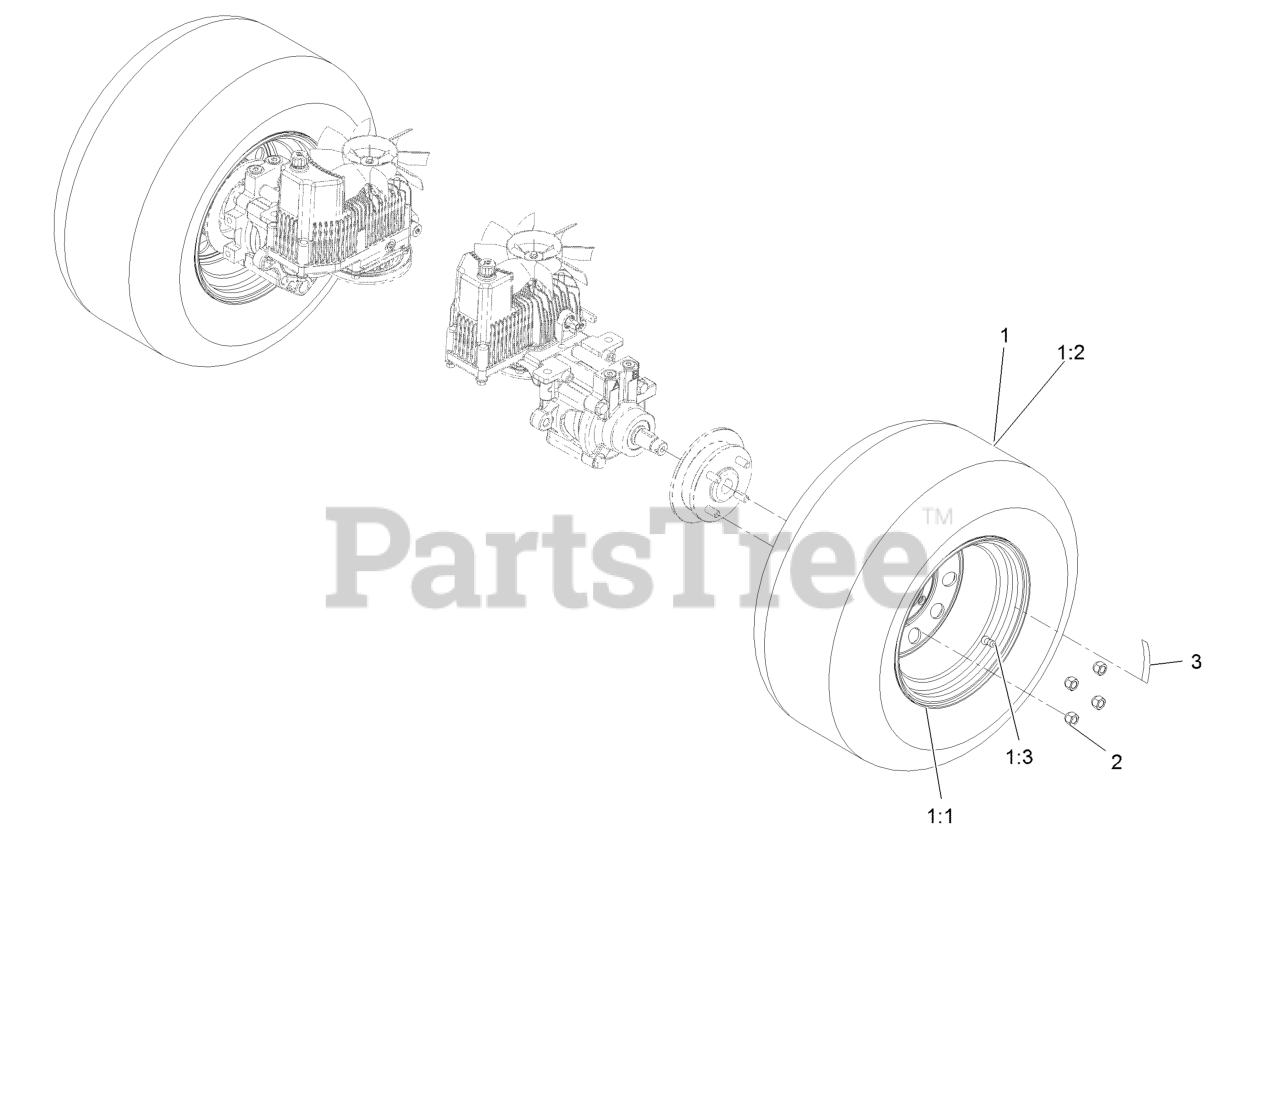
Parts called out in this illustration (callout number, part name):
1	ASM-Wheel And Tire
1:1	ASM-Rim 72
1:2	Tire-Drive
1:3	Stem-Valve
2	Nut-Lug 1/2-20
3	Decal-Torque, Wheel Hub Lug
